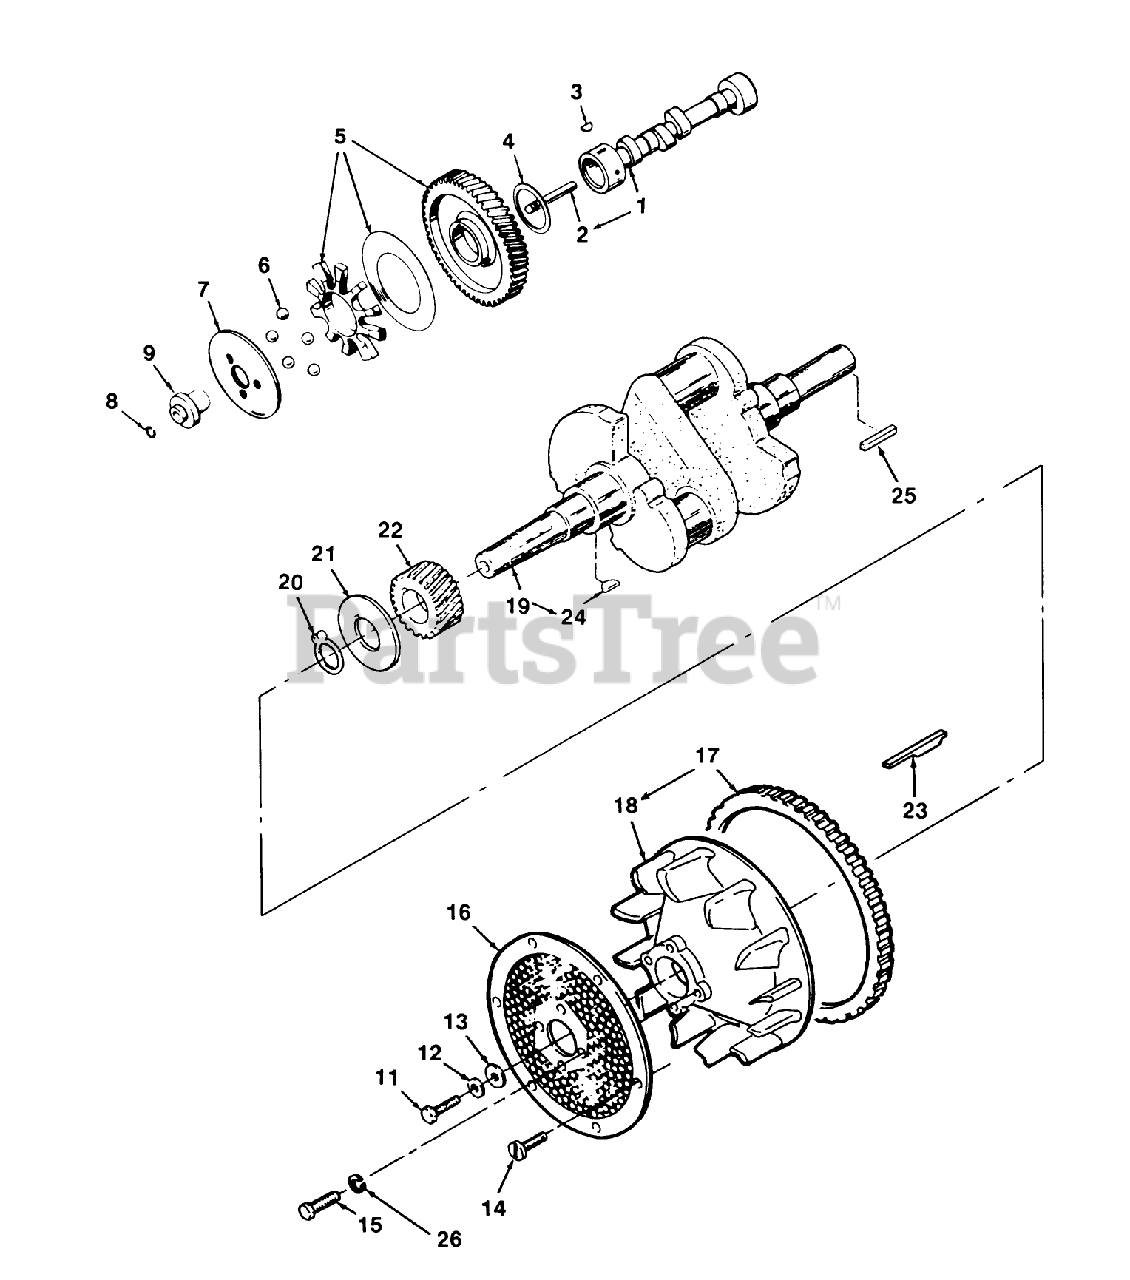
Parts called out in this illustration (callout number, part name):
1	CAMSHAFT
2	PIN-CENTER
4	WASHER-THRUST
6	BEARING
7	CUP-GOVERNOR
9	HUB-GOVERNOR CUP
12	WASHER-FLAT
13	WASHER-FLAT
15	HX HD LOCK CAPSCREW
16	SCREEN-AIR INLET
18	FLYWHEEL
22	GEAR-CRANKSHAFT
23	KEY-FLYWHEEL
